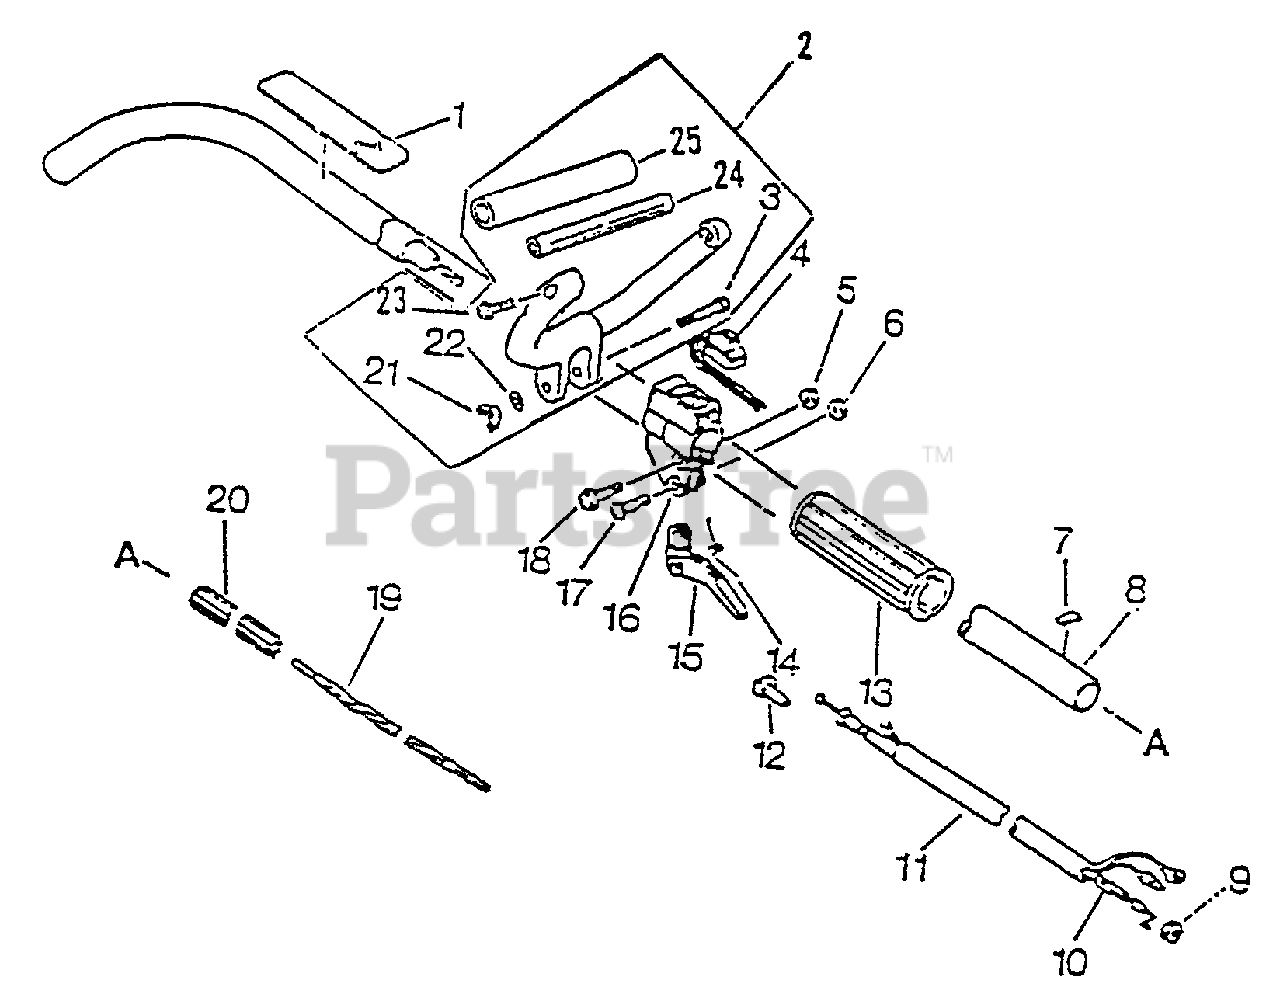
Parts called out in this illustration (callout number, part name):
1	LABEL - CAUTION
2	LOOP HANDLE ASSY
3	BOLT - 6×40
4	IGNITION SWITCH ASSY
5	NUT M5
6	NUT, LOCK M5
7	LABEL - ALIGNMENT
8	PIPE, MAIN
10	CABLE, THROTTLE
12	GUIDE, CABLE
14	SPRING, THROTTLE
15	TRIGGER, THROTTLE
16	BRACKET, THROTTLE CONTROL
18	SCREW 5×28
19	DRIVESHAFT - FLEXIBLE
20	LINER - FLEXIBLE
21	NUT, WING 6
22	WASHER 6.5×11.5×0.8
23	SCREW 5×30
24	BRACKET, HANDLE
25	GRIP, HANDLE
